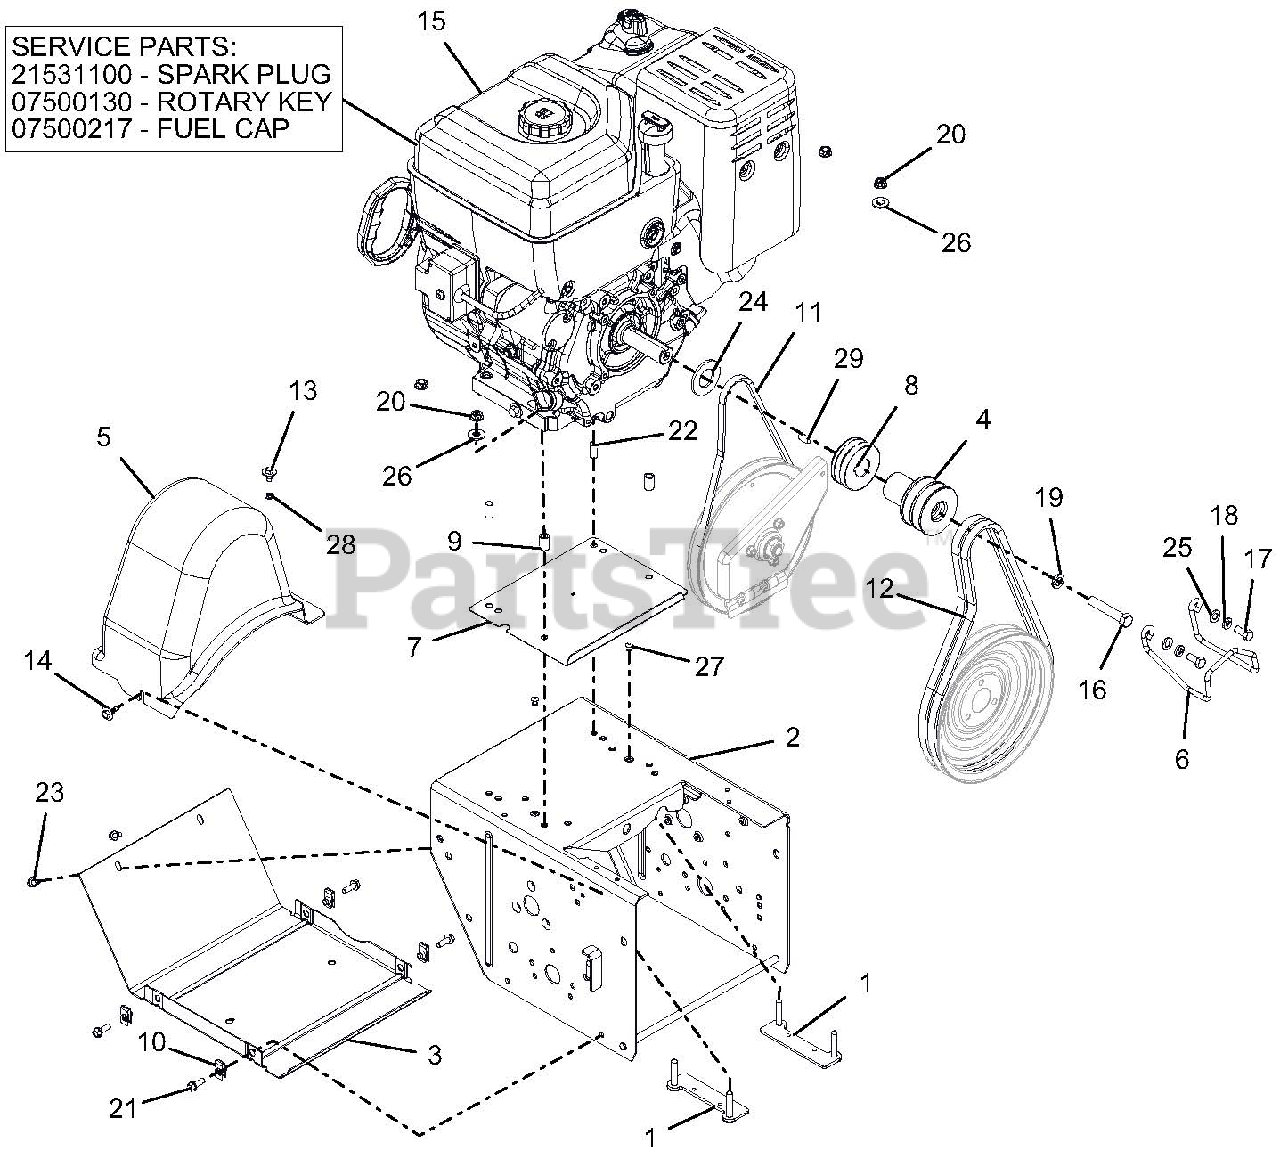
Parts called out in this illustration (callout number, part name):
1	BOLT STRAP, 2100 BRIGGS
2	PRO HYDRO FRAME, MAIN
3	COVER, BOTTOM
4	SHEAVE, ATTACHMENT 2-GRV
5	COVER, BELT-LARGE PRO
6	FINGER, BELT
7	BAFFLE,ENGINE-PRO SERIES
8	SHEAVE, DRIVE
9	BSHG-SLV .328X.50X.75
10	NUT-RTNR .25-20X.56
11	V-BELT, 3L-WRAPPED
12	V-BELT, HA-RAW EDGE (SET)
13	SCR-TAP .25-20X.50 LGHWH TR YZ
14	SCR-TAP .25-20X.5 CAPTIVE
15	ENGINE, BRIGGS PF 2100, 120V
15	PLUG, SPARK 20HP B&S VANGUARD
15	KEY, IGNITION ROTARY B&S
15	CAP, FUEL - BRIGGS & STRATTON
16	BLT-HEX .44-20X2.50 GR5 YWZC
17	BLT-HEX .31-24X.75 YWZC GR5
18	WSHR-LK .312X.097 HVY YWZC
19	@WSHR-LK .44X.109 REG YWZC
20	@NUT-LK-CTR-FLG .31-18 YZ GR F
21	BLT-HEX .25-20X.75 HWH YZ GR5
22	BSHG-SLV .325X.400X.795
23	SCR-TAP .25-20X.50 HWH TR YWZ
24	WSHR-FL-STL- 1.062X2.0X.134 YZ
25	@WSHR-FL-STL.344X.688X.065YWZC
26	@WSHR-FL-STL.38X.875X.083 YWZC
27	RVT-POP .187 YZ
28	NUT-PUSH .25X.50 O.D.
29	KEY-SQ .25X.625X.25 SAE 8630
